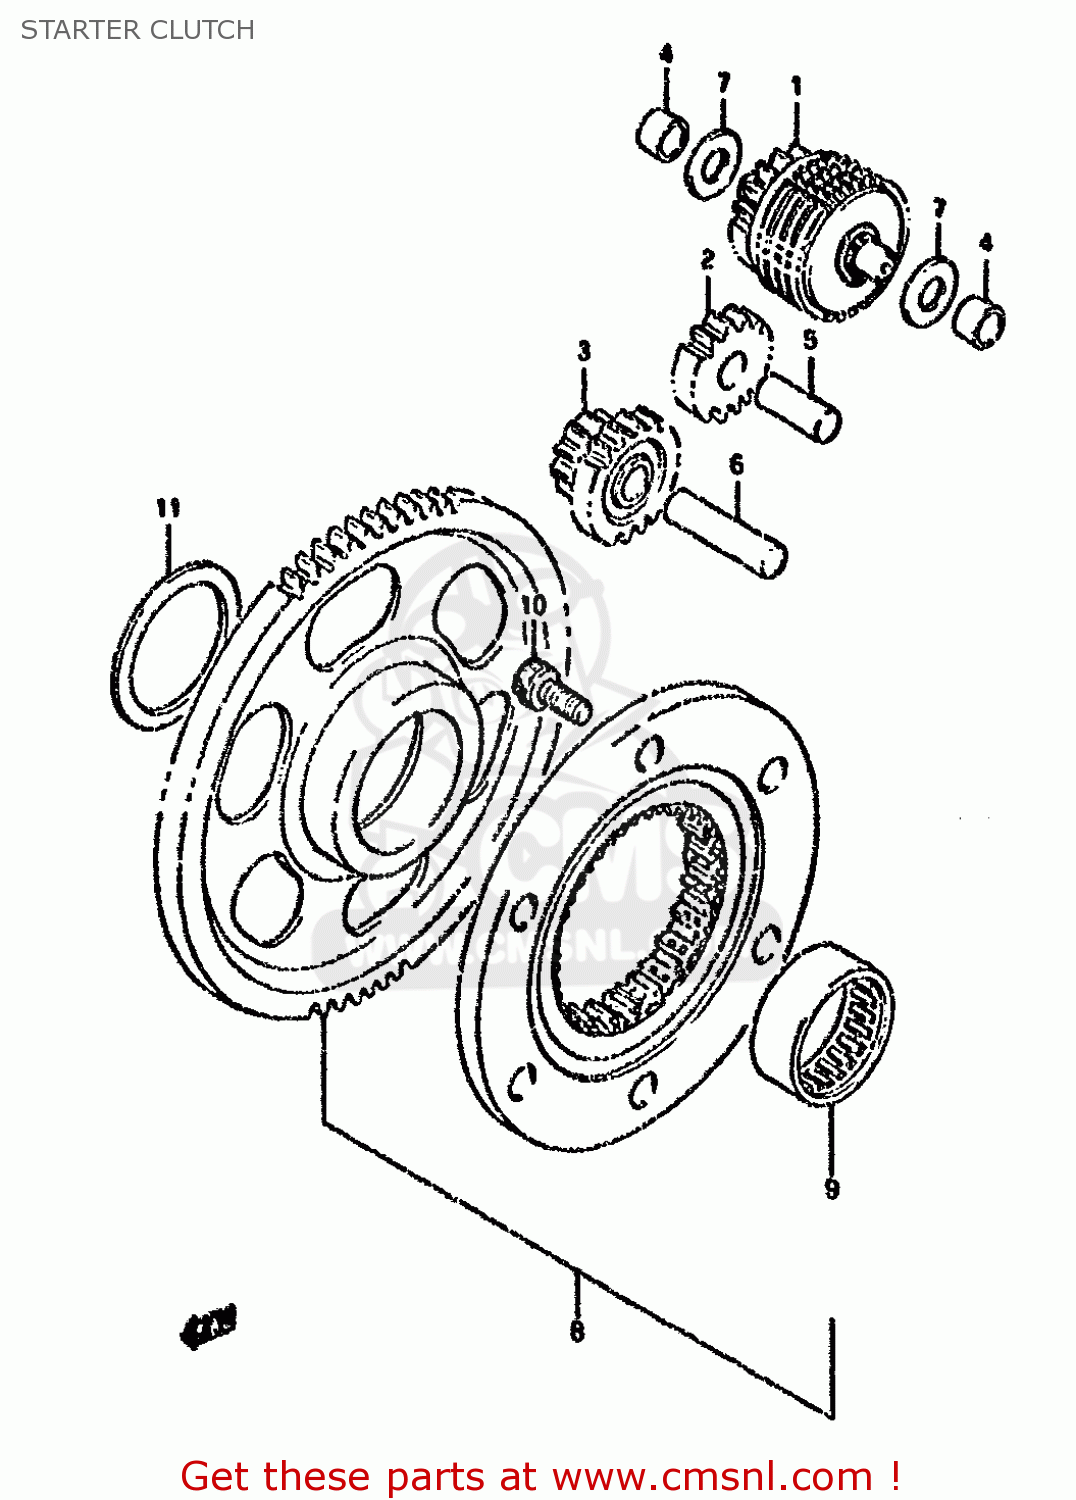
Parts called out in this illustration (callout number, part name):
1	LIMITER ASSY,S
2	GEAR,STARTER IDLE NO.2
3	GEAR,STARTER IDLE NO.3
4	BUSH,LIMITER GEAR SHAFT
5	PIN
6	PIN
7	WASHER
8	CLUTCH SET,STARTER
9	BEARING(35X43X18)
10	BOLT
11	WASHER
